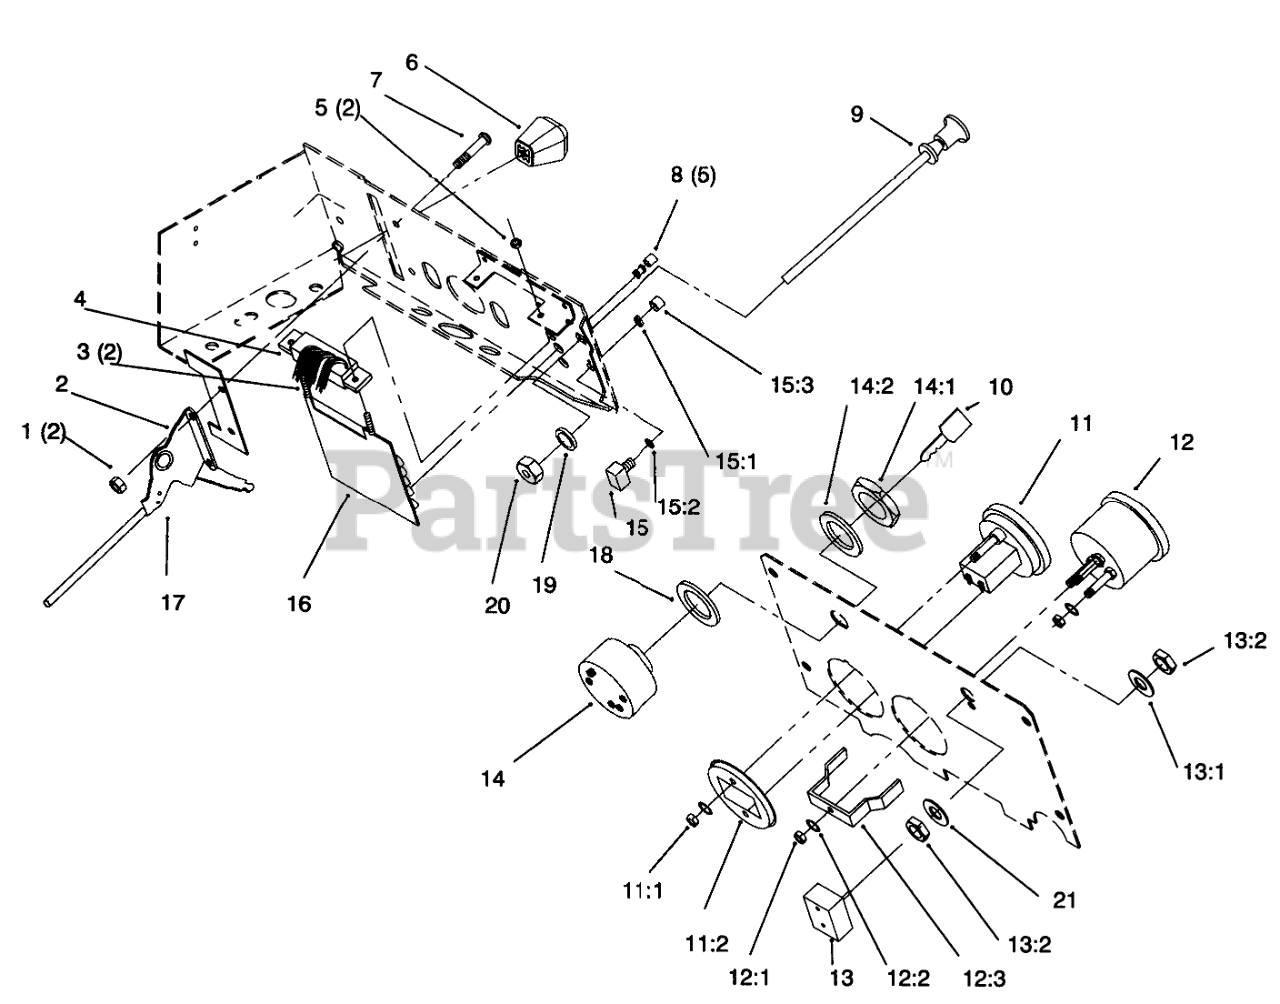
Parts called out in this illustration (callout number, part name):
1	Nut
2	Washer
7	SCRW-PHC
9	CONTROL CHOKE
10	KEY-IGNITION
11	Hourmeter
13	SWITCH-LIGHTS
14	KEY SWITCH ASM
17	CONTROL-THROTTLE
18	WASHER
19	WASHER-FLAT
20	NUT-HEX PALNUT
21	WASHER
